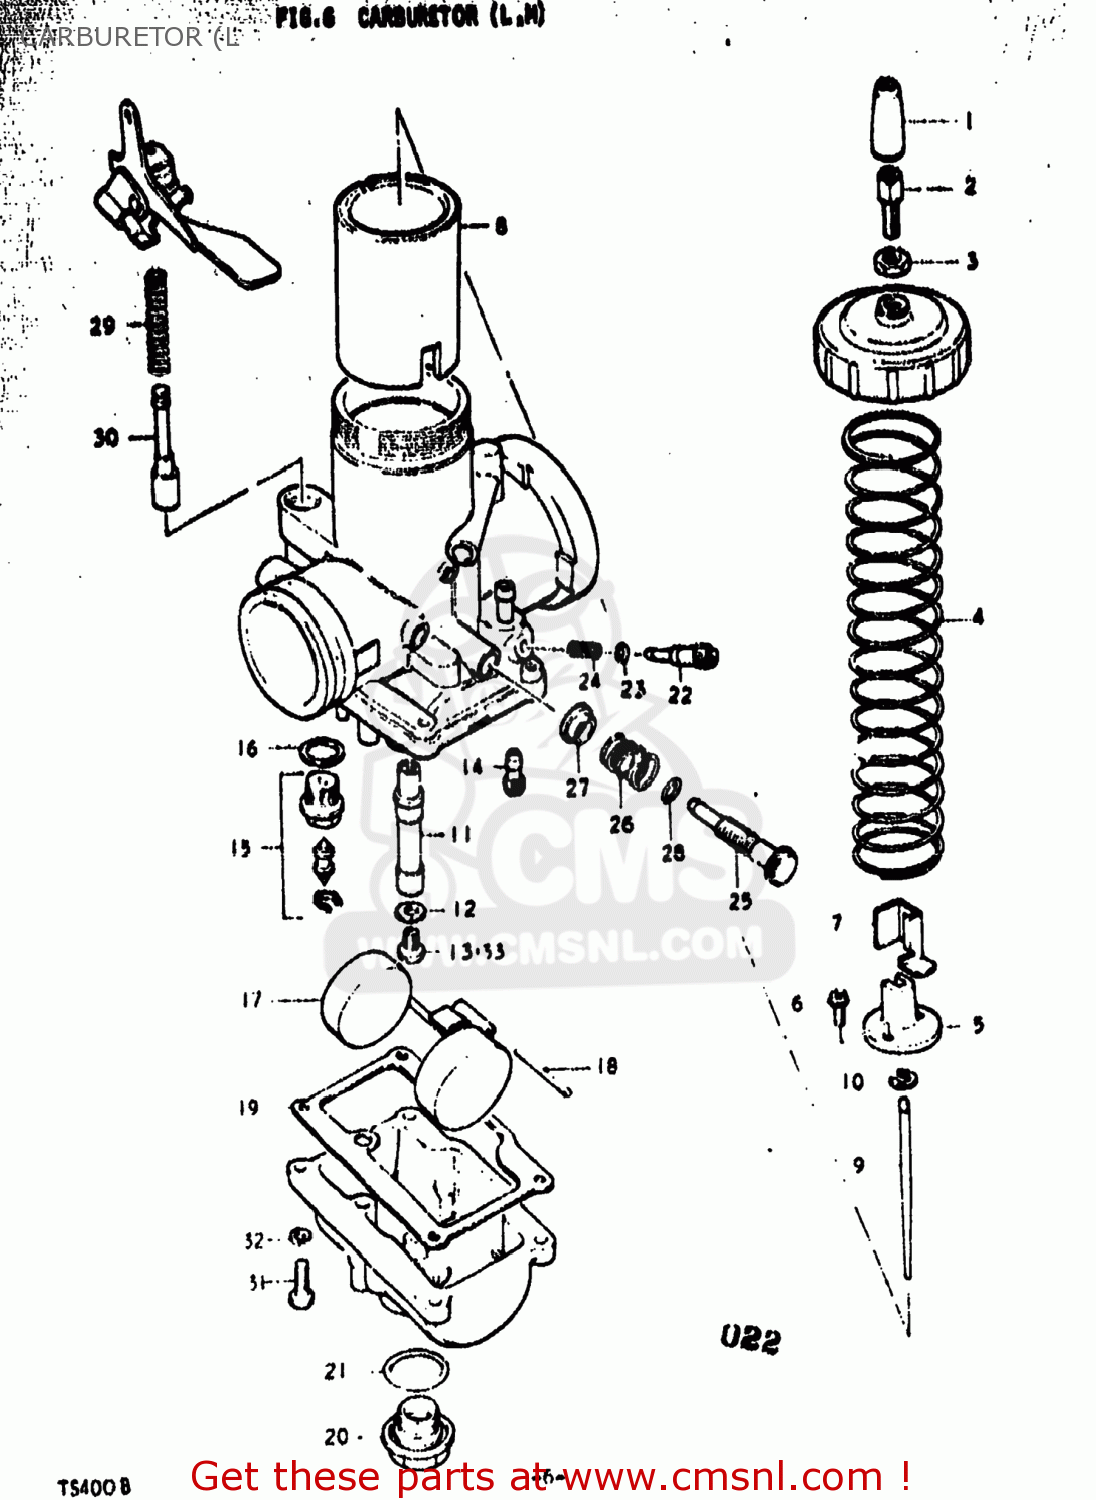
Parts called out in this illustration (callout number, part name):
0	CARBURETOR ASSEMBLY
1	CAP,CABLE ADJUSTER
2	ADJUSTER,CABLE
3	NUT
4	SPRING
5	CONNECTOR
6	SCREW
7	CLIP
9	NEEDLE JET
10	CLIP
11	JET,NEEDLE
12	WASHER
13	JET
14	JET
15	VALVE ASSEMBLY,NEEDLE
16	GASKET,MAIN JET HOLDER (NAS)
17	FLOAT
18	PIN,FLOAT
19	GASKET,FLOAT CAHMBER (NAS)
20	SCREW,GUIDE
21	RING
22	SCREW, PILOT AIR
23	O RING
24	SPRING
25	ADJUSTER
26	SPRING,THROTTLE STOP
27	COVER
28	O-RING
29	SPRING
30	PLUNGER,STARTER
31	SCREW
32	LOCK WASHER
33	JET
